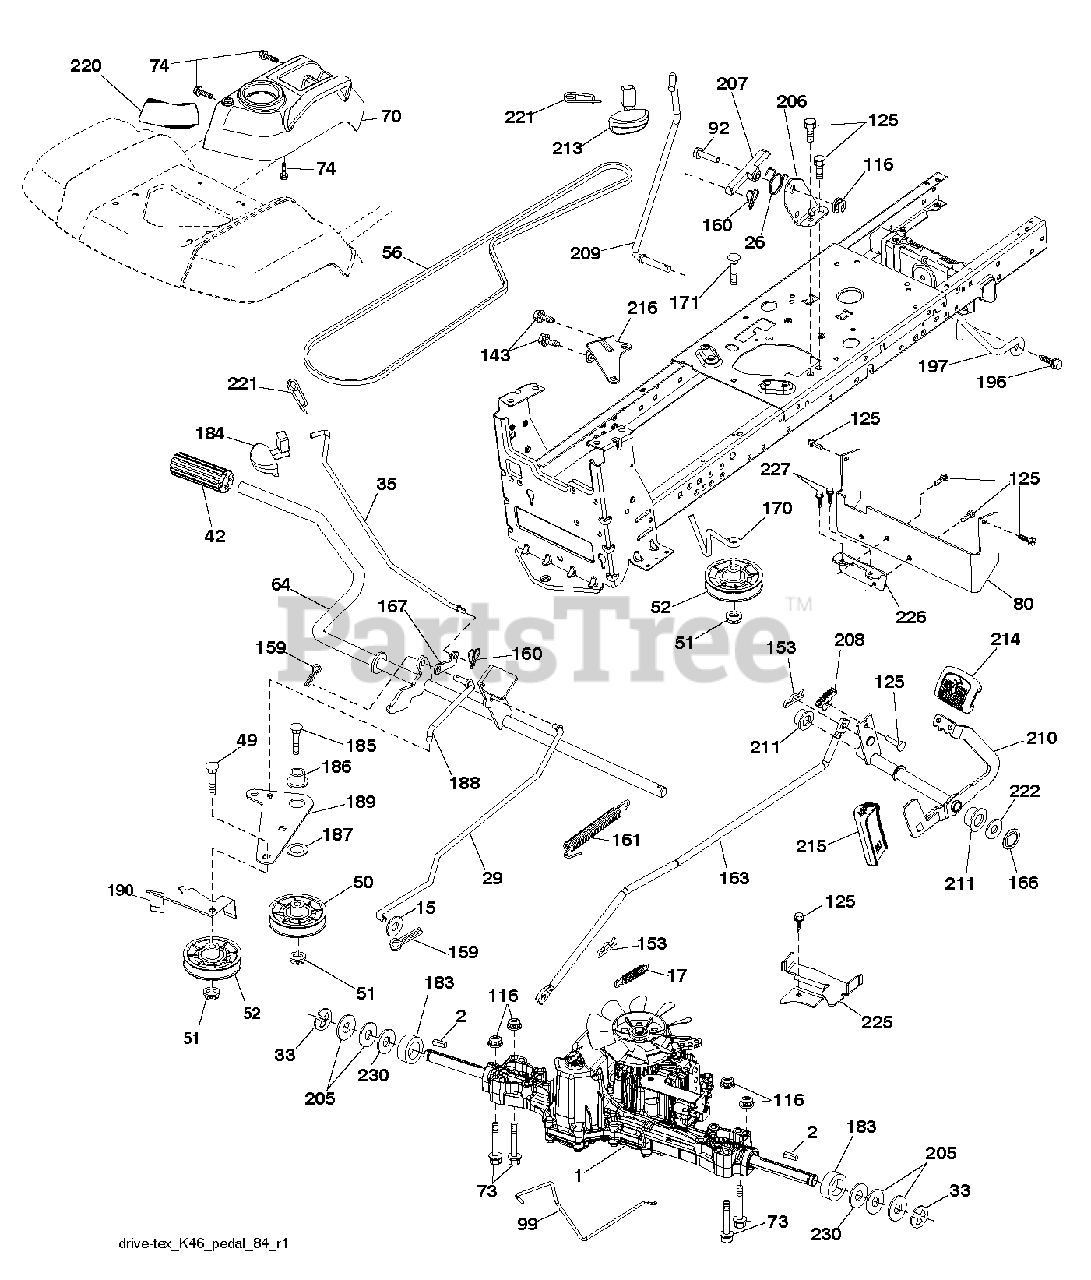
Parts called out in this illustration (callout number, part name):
2	SQUARE KEY
15	WASHER
17	SPRING.BRAKE.K46.GREEN
26	SPRING.RETURN.CRUISE
29	ROD.BRAKE.K46
35	ROD.BRAKE.PARTK.HUSQ.TEX
42	PEDAL COVER T
50	IDLER.FLAT.910.OFFSET
51	NUT LOCK FLG 3/8-16 UNC
52	IDLER.V-GROOVE.910.OFFSET
56	V-BELT.MOWER.92.40.42/K46
64	SHAFT.ASM.PEDAL.BRK.CNTR
70	CONSOLE.ASM.RH.GT.FC.HUSQ
74	SCREW.HI-LO.CONSOLE
80	STRAP.TORQUE.K46.K57R.TT
92	BOLT
99	ROD.SPRING.BYPASS.K46.LT.Z
116	NUT LOCK HEX FLANGE 5/16-18
125	SCREW
143	SCREW LT
153	RETAINER M
159	COTTER PIN
160	RETAINER CLIP
161	SPRING, RETURN LT
163	ROD.CONTROL.PEDAL.K46
166	NUT.PUSH.625
167	LATCH.BRAKE.SPRING
170	KEEPER.V-IDLER.CENTER.
183	SPACER AXLE
184	RB HANDLE.PARKG.BRK.HUS/PRED
186	SPACER.RETAINER
187	WASHER 12/32X2X10GA
188	RP LINK.CLUTCH.GROUND.DRIVE
189	BELLCRANK.GROUND.DRIVE.TEX.
190	KEEPER.BELLCRANK.DRIVE
196	SCREW 3/8-16X1
197	LINK.CLUTCH.ANIT-ROTAT
206	BRKT.MOUNT.LATCH.CRUIS
207	LATCH.CONTROL.CRUISE
208	GEAR.SECTOR.CONTROL.CR
209	ROD.CONTROL.CRUISE.GT.
210	ROCKER.ASM.PEDAL.CONTR
211	BEARING.NYLON
213	KNOB.CONTROL.CRUSIE.HU
214	PEDAL.FORWARD.PAD.TEX
215	PEDAL.REVERSE.TEX.GT.4
216	BRACKET.PULLEY.IDLER.W/TEX
220	REFLECTOR.RH.TEX GT
221	RETAINER.SPRING.CLIP.H
222	WASHER 21/32 X 1-1/4 X 10 GA.
225	KEEPER.BELT.TRANSAXLE.K46
226	BRACKET.MOUNT.TORQUE.K46.TLT
227	SCREW
230	WASHER.HARDENED
